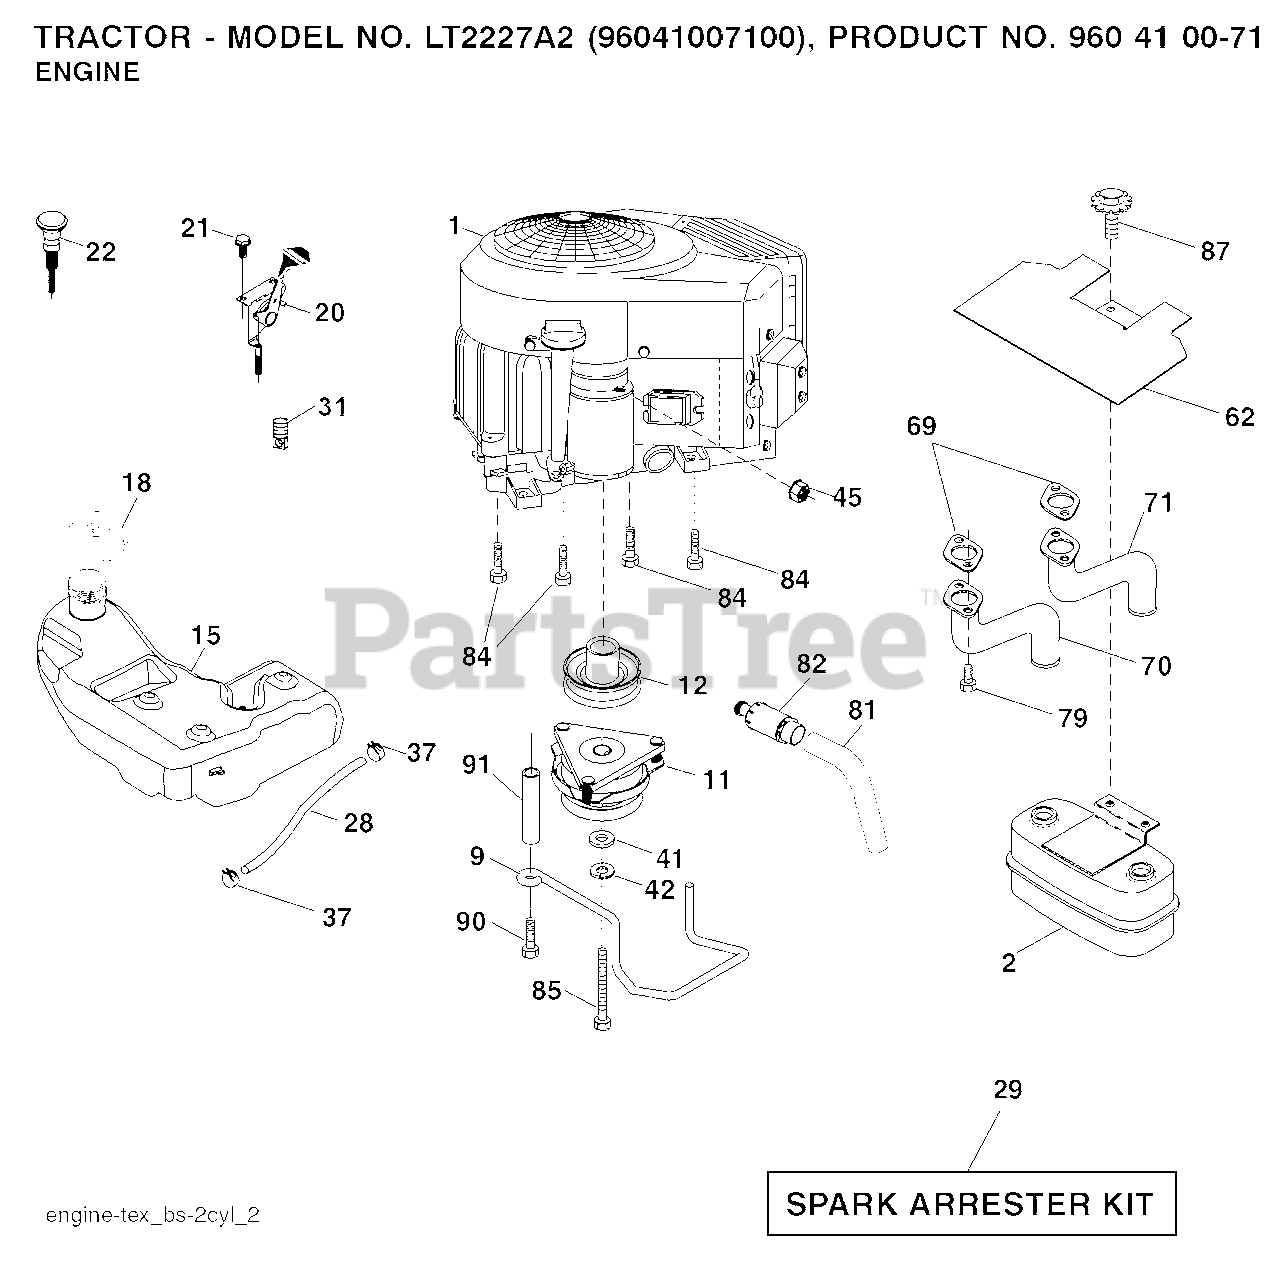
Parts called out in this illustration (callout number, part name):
2	MUFFLER.TWIN.CYL.LOW.TONE
9	KEEPER.BELT.ENGINE.4.2
11	CLUTCH ELECTRIC
12	PULLEY ENGINE
15	TANK.FUEL.4GAL
18	CAP.ASM.FUEL.TANK.3"BL
20	THROTTLE CABLE
21	SCREW.#10 X 0.750.BOS THREAD
22	CONTROL CHOKE
29	ARRESTER SPARK (OPTIONAL)
31	PUSH CLIP
37	HOSE CLAMP
42	LOCKWASHER
45	NUT
62	RP SHIELD HEAT MUFFLER
69	GASKET.MUFFLER
70	TUBE MANIFOLD LH
71	EXHAUST TUBE RH
79	SCREW.SOCKET.HEAD.5/16-18
81	TUBE, DRAIN OIL ASM.
82	PLUG DRAIN OIL EASY
84	SCREW.3/8-16
85	BOLT HEX 7/16-20 X 3.75 GR. 5
87	BOLT.5/16-18UNCX1.W/SEMS.BLK
90	SCREW 3/8-16X1
91	BUSHING.1.375OD
